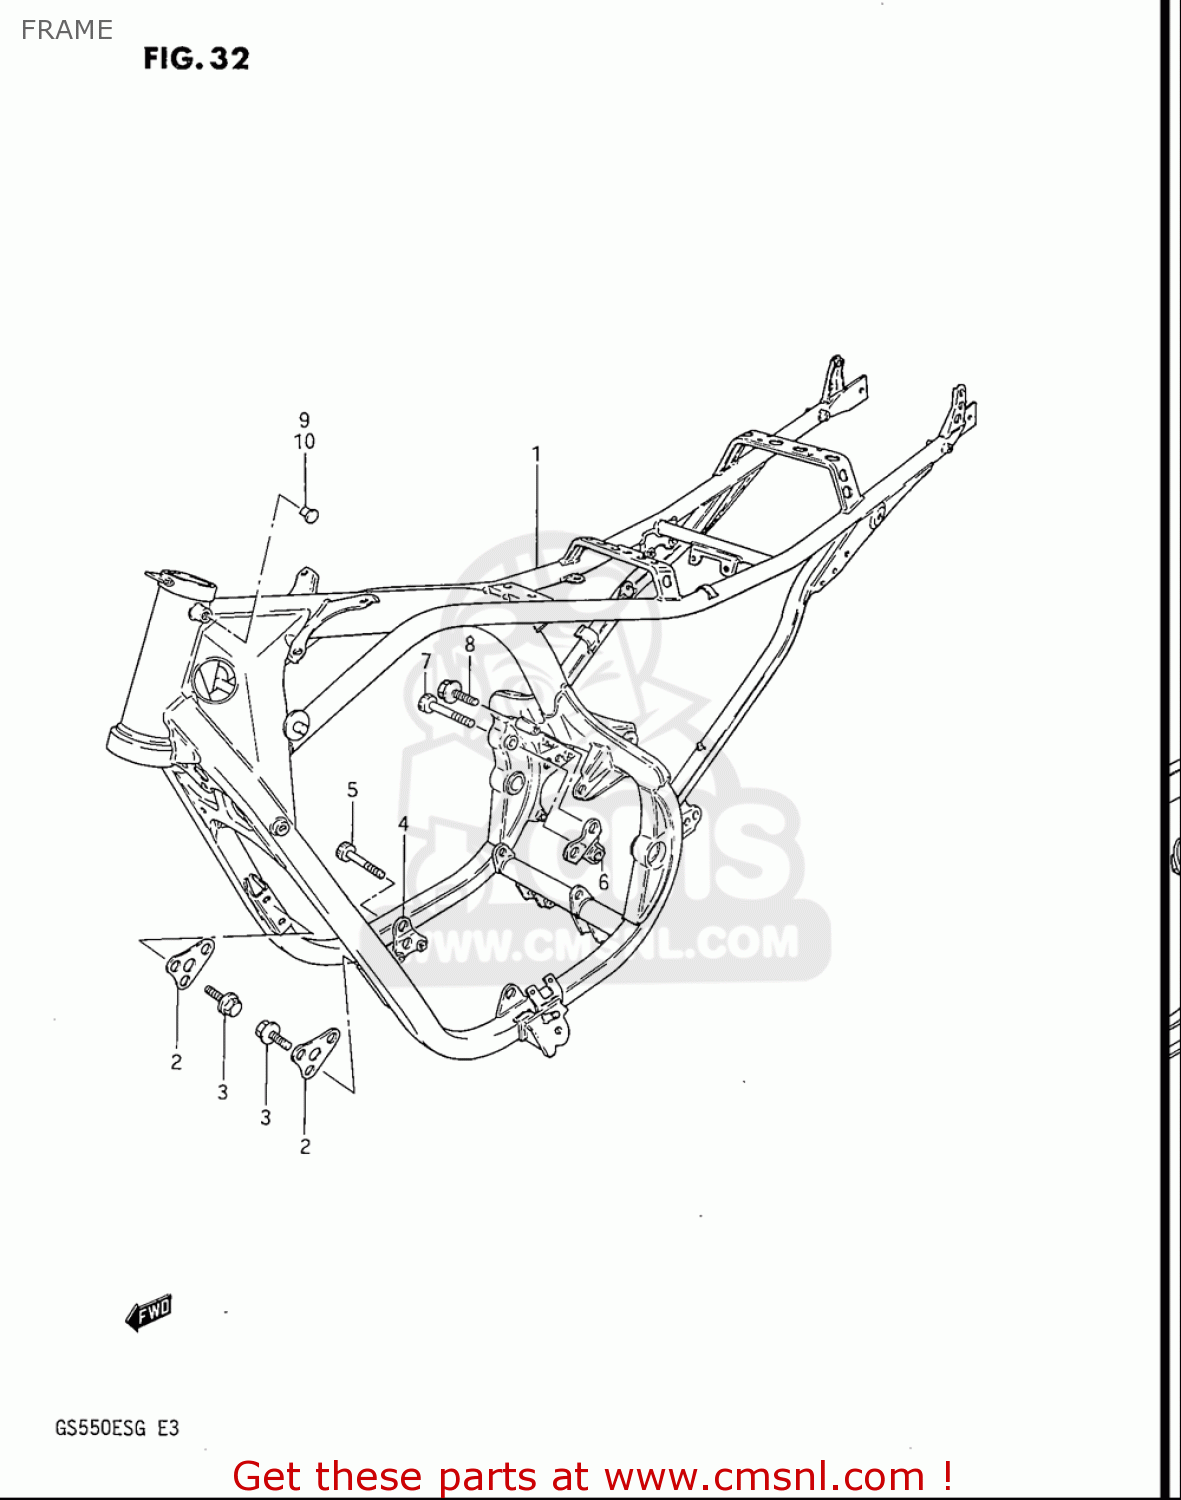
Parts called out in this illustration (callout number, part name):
3	BOLT
5	BOLT
7	BOLT
8	BOLT
9	PLUG(OD:12)
10	CAP
